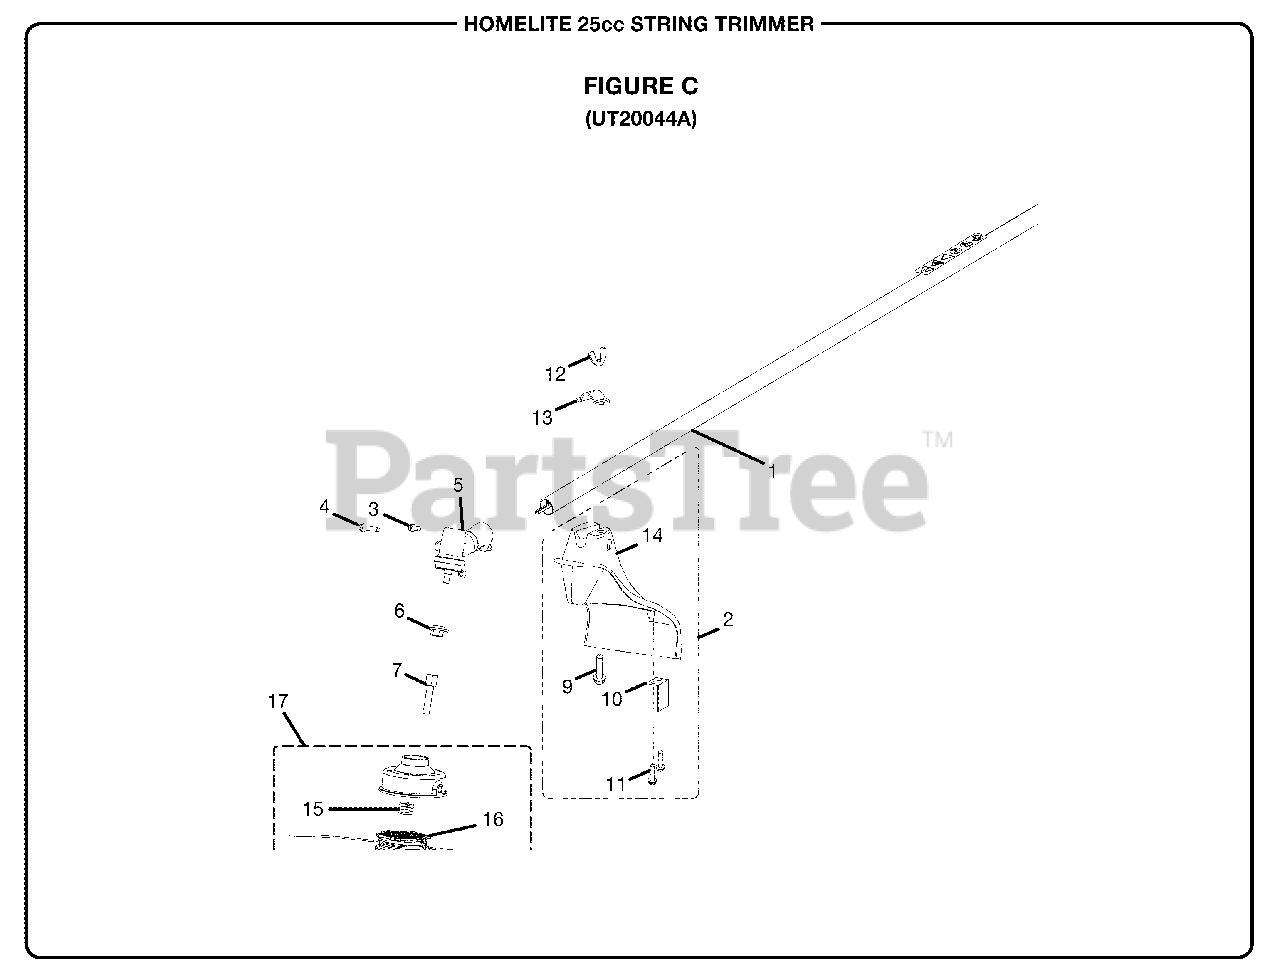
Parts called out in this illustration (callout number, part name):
1	STRAIGHT SHAFT ASSEMBLY
2	GRASS SHIELD ASSEMBLY
3	SCREW (10-24 x 5/8 in.)
4	SCREW (1/4-20 x 1-1/4 in.)
5	GEAR HEAD
6	WASHER
7	SHAFT ADAPTER
8	SPOOL RETAINER (LH)
9	SCREW, SQUARE HEAD
10	CUT OFF BLADE
11	SCREW
12	WING NUT
13	SHIELD CLAMP
14	GRASS SHIELD
